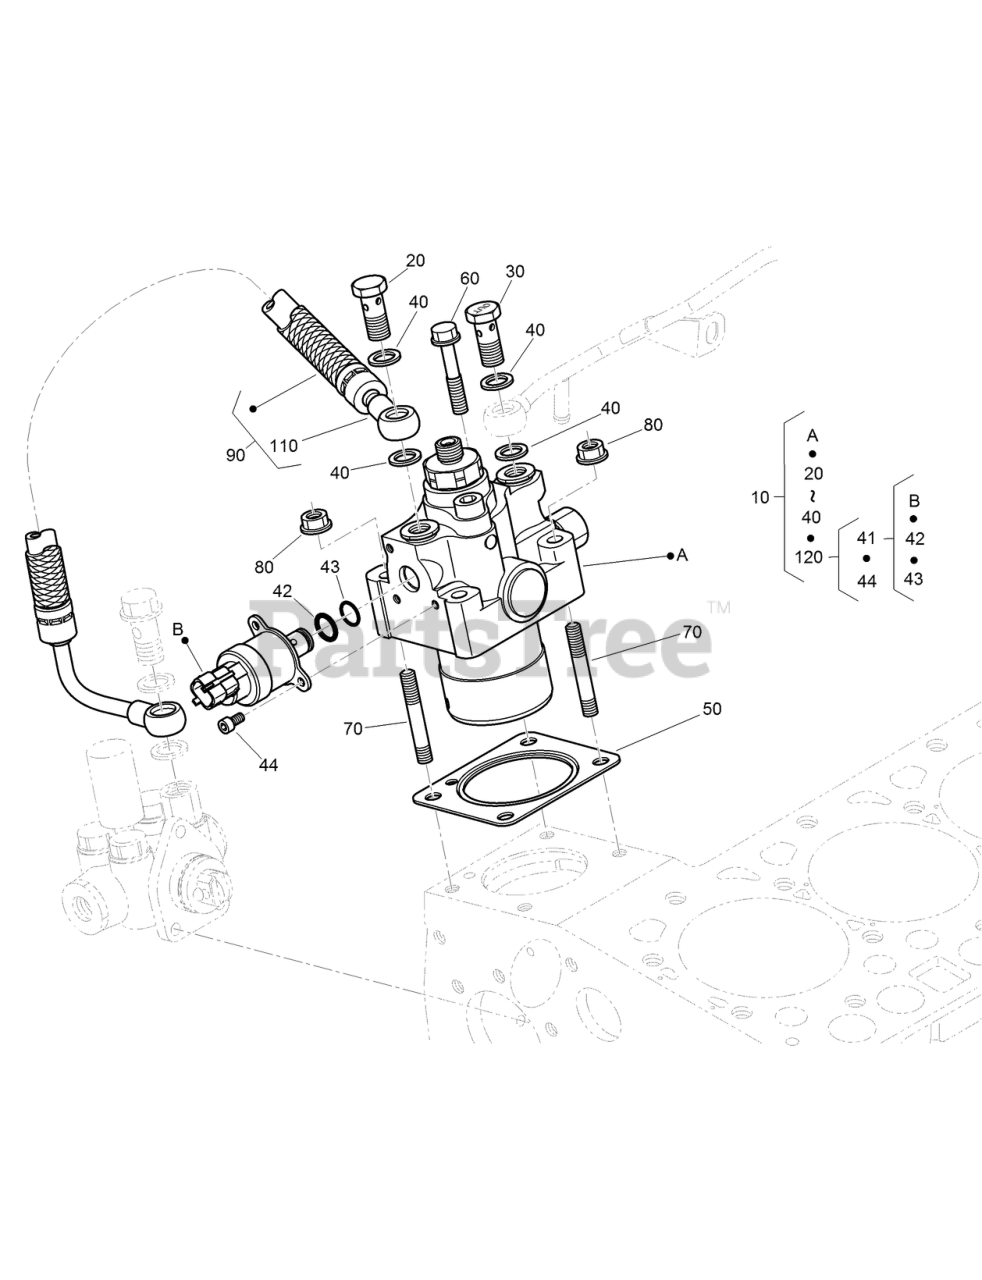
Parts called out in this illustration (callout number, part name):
10	SUPPLY PUMP ASM
20	BOLT-JOINT
30	BOLT-JOINT
40	GASKET
41	VALVE ASM
42	O-RING (SCV 1)
43	O-RING (SCV 2)
50	GASKET-PUMP
60	BOLT-FLANGE
80	NUT-FLANGE
90	FUEL HOSE ASM
110	FUEL HOSE
120	VALVE KIT
